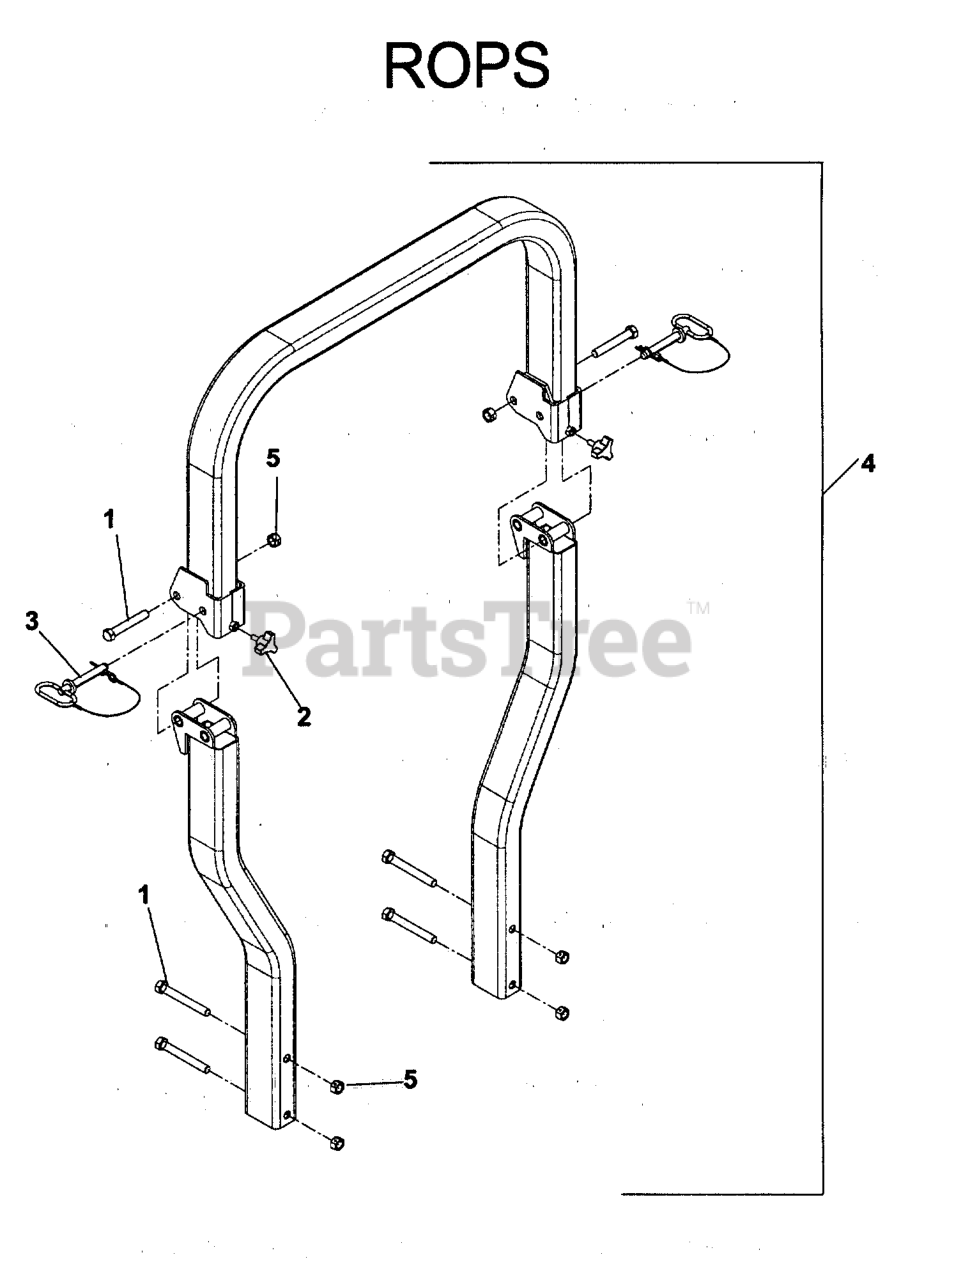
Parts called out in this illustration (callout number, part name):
1	HCS 1/2C X 3 1/4
2	KNOB W/STUD
3	PIN, 1/2" W/LANYARD
4	ROPS, COMPLETE W/ SEAT BELT
5	NUT 1/2-13 HEX CNTRLK GR 5 ZD
